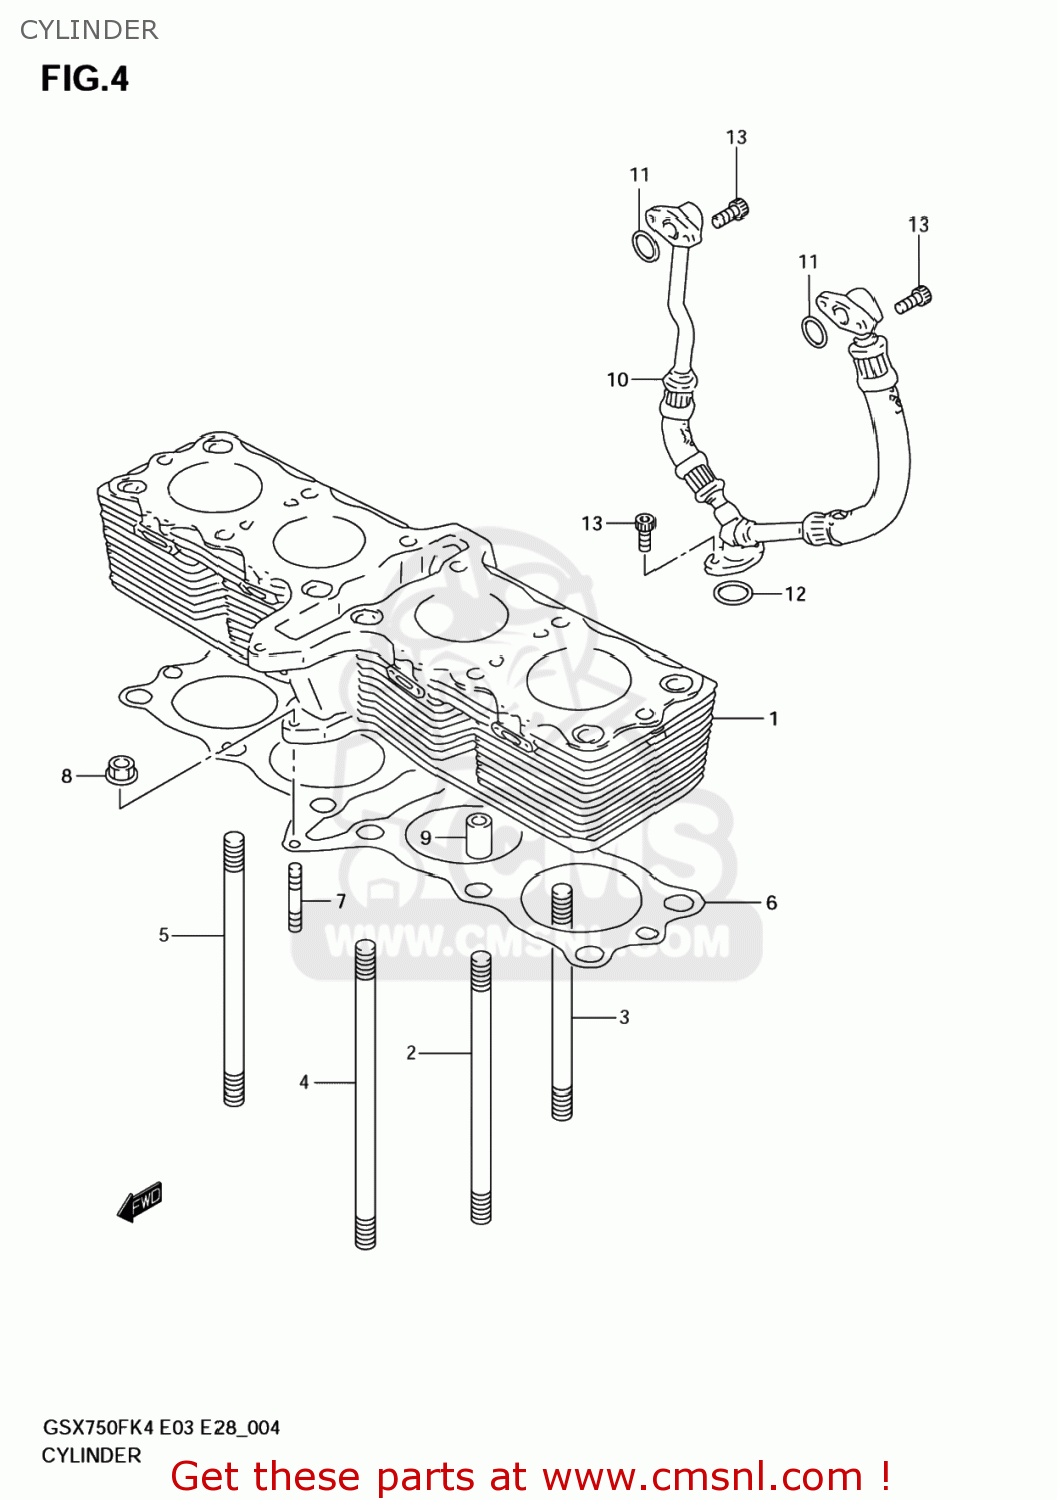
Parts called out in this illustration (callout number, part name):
1	CYLINDER
2	BOLT,STUD
3	BOLT,STUD
4	BOLT,STUD
5	BOLT,STUD
6	GASKET,CYLINDER (NAS)
7	STUD,M6X1X32
8	NUT
9	PIN(13X10.4X20)
10	HOSE,OIL HEAD COOLER
11	O RING(D:2.5,ID:13.8)
12	O RING(D:2.4,ID:15.8)
13	BOLT,OIL FILLE
